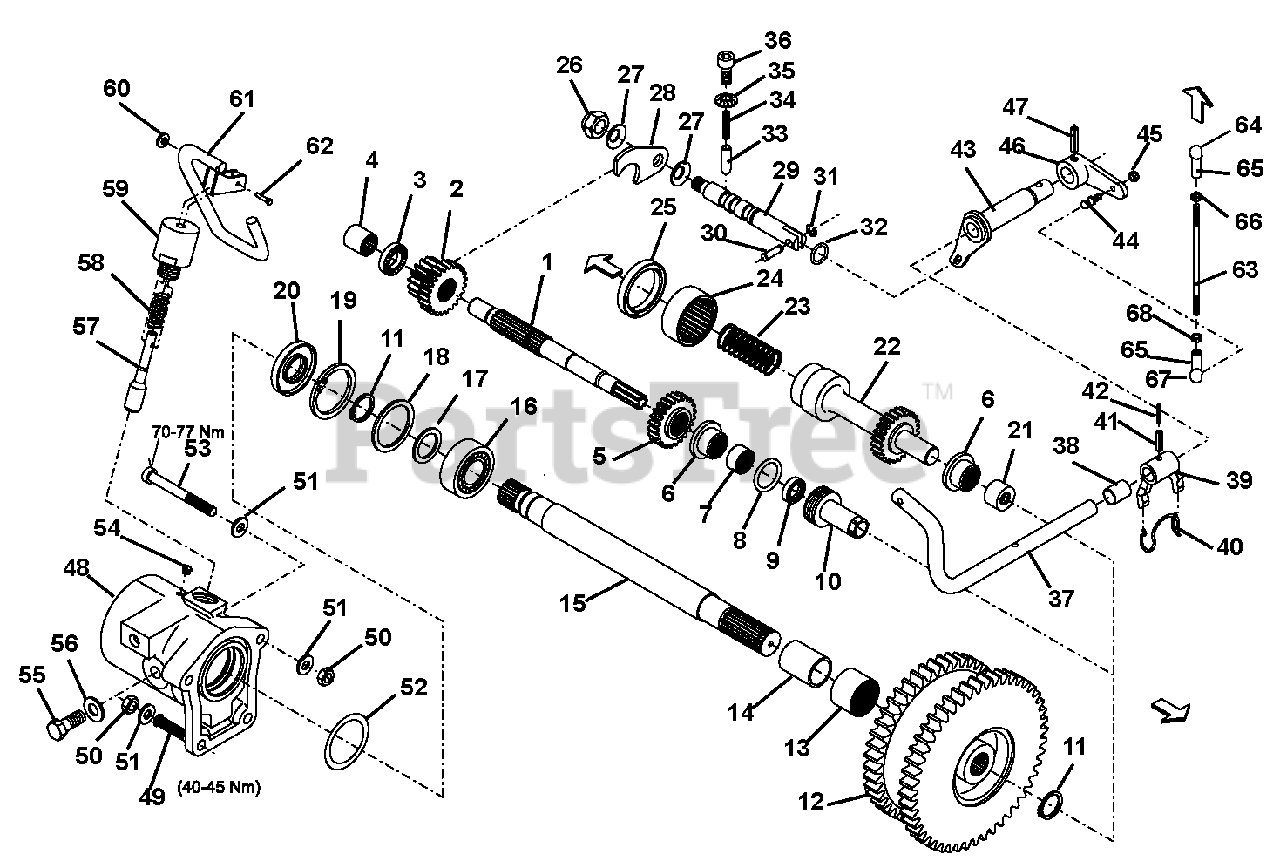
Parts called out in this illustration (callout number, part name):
1	Shaft, Clutch
2	Gear, Clutch
3	Ball Bearing
4	Needle Bearing, Black 1622
6	Ball Bearing, RAX 718
7	Needle Bearing, HK 1812
8	O-Ring, D3770 27 x 3
9	Oil Seal, 16 x 24 x 6 B1
10	Bushing, Guide
11	Circlip, D471 24 1,20
12	Pinion, Double, Z=83/88
13	Bearing, Needle HK 3026
14	Ring, Inner IR 25 x 30 x 38.5
15	Shaft, PTO
16	Bearing, Ball, 4205B.TVH
17	Washer, D988 25 x 35 x 2
18	Supporting Ring, D988 42
19	Circlip, D472 52 2,00
20	Seal, Oil 25 x 52 x 7
21	Needle Bearing, Black 1816
22	Drive Shaft
23	Pressure Spring
24	Needle Bearing, HK 4520
25	Oil Seal, 42 x 55 x 8
26	Nut, Lock, D980V M12
28	Gear Shift
29	COntrol Rod
33	Pin, Lock
34	Spring, Pressure
35	Washer, FORM Steel 10.2/20.25 x 1.6
36	Screw, Cylinder D912 M10 x 12
37	Shaft Clutch
38	Bearing Sleeve
39	Lever, Clutch Release
40	Spring, Lock
41	Pin, Heavy D1481 5 x 20
42	Pin, Heavy D1481 3 x 20
43	Stay Shift
44	Joint Ball Pin
45	Nut, Lock D985 M6
47	Pin Heavy, ISO 8752 6 x 30
48	Case PTO
49	Threaded Pin D913 M10 x 70
50	Hex Nut, D6330B M10 x 15
51	Friction Washer
52	O-Ring D3770 50, 39 x 3,55
53	Screw, Cylinder D912 M10 x 75
54	Lubricating, D71412B M10
55	Hex Bolt D933 M10 x 12
56	Washer M14
57	Bar, Lock
58	Spring, Pressure 1.6/15.1 x 60
59	GUide Tube
60	Circlip, BQ-DL5
62	Pin, LOck D1444A 5 x 25
63	Rod, THreaded M6 x 177
64	Pan, Ball
65	Bow, Lock D71805 10S
66	Nut, HEx D934 M6
67	Pan, Ball D71805 10B
68	Hex Nut, D934 M6
